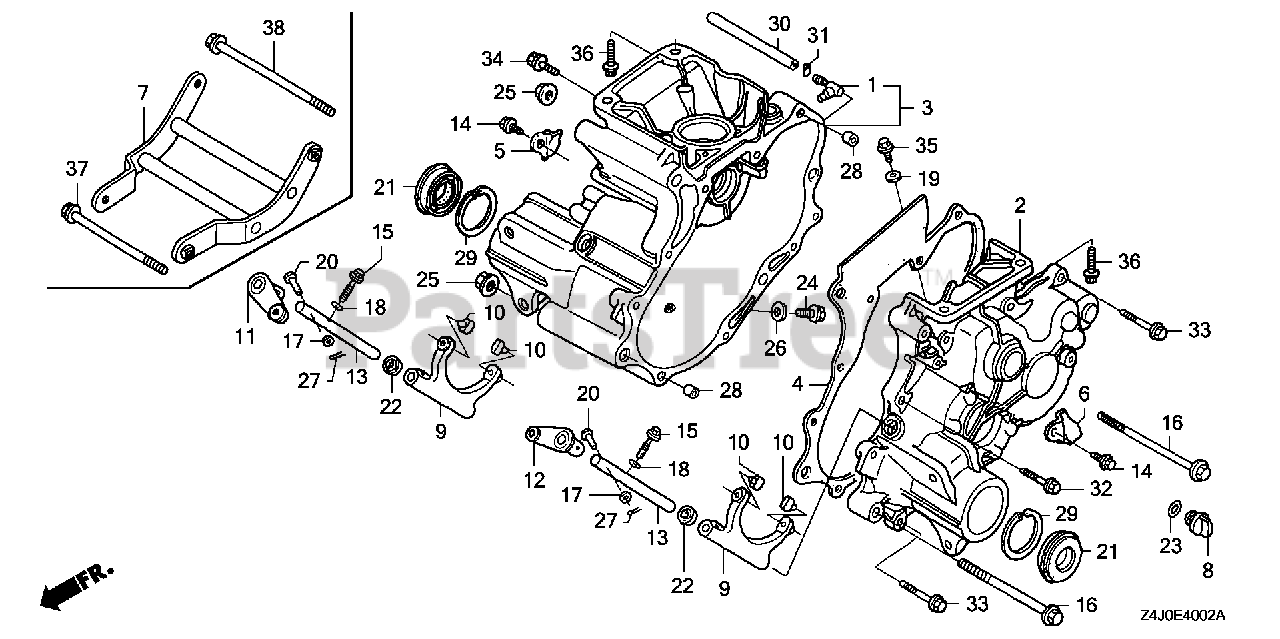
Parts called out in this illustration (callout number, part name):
1	JOINT, BREATHER
2	CASE, R. TRANSMISSION
3	CASE, L. TRANSMISSION
4	GASKET, TRANSMISSION CASE
5	PLATE, R. SIDE CLUTCH
6	PLATE, L. SIDE CLUTCH
7	GUARD, TRANSMISSION
9	FORK, SIDE CLUTCH
11	ARM, R. SIDE CLUTCH
12	ARM, L. SIDE CLUTCH
13	SHAFT, SIDE CLUTCH ARM
14	BOLT, FLANGE (6X12) (CT200)
15	BOLT, SPECIAL
16	BOLT, ALTERNATOR
17	WASHER (10MM)
18	WASHER, CONICAL SPRING (6MM)
19	WASHER, SEALING (8MM)
20	PIN, AUXILIARY CHANGE LEVER
21	SEAL, WATER (25X52X9.5) (NOK)
22	OIL SEAL (12X18X4.2)
23	O-RING (16MM)
24	BOLT, DRAIN PLUG (12MM)
25	NUT, FLANGE (10MM)
26	WASHER, DRAIN PLUG (12MM)
27	PIN, SPLIT (2.0X12)
28	PIN, DOWEL (8X14)
29	CIRCLIP (INNER) (52MM)
30	BULK HOSE, FUEL (4.5X3000) (4.5X150)
31	CLIP, TUBE (B8)
32	BOLT, FLANGE (6X32)
33	BOLT, FLANGE (6X40)
34	BOLT, FLANGE (8X12)
35	BOLT, FLANGE (8X16)
36	BOLT, FLANGE (8X30)
37	BOLT, FLANGE (10X125)
38	BOLT, FLANGE (10X160)
